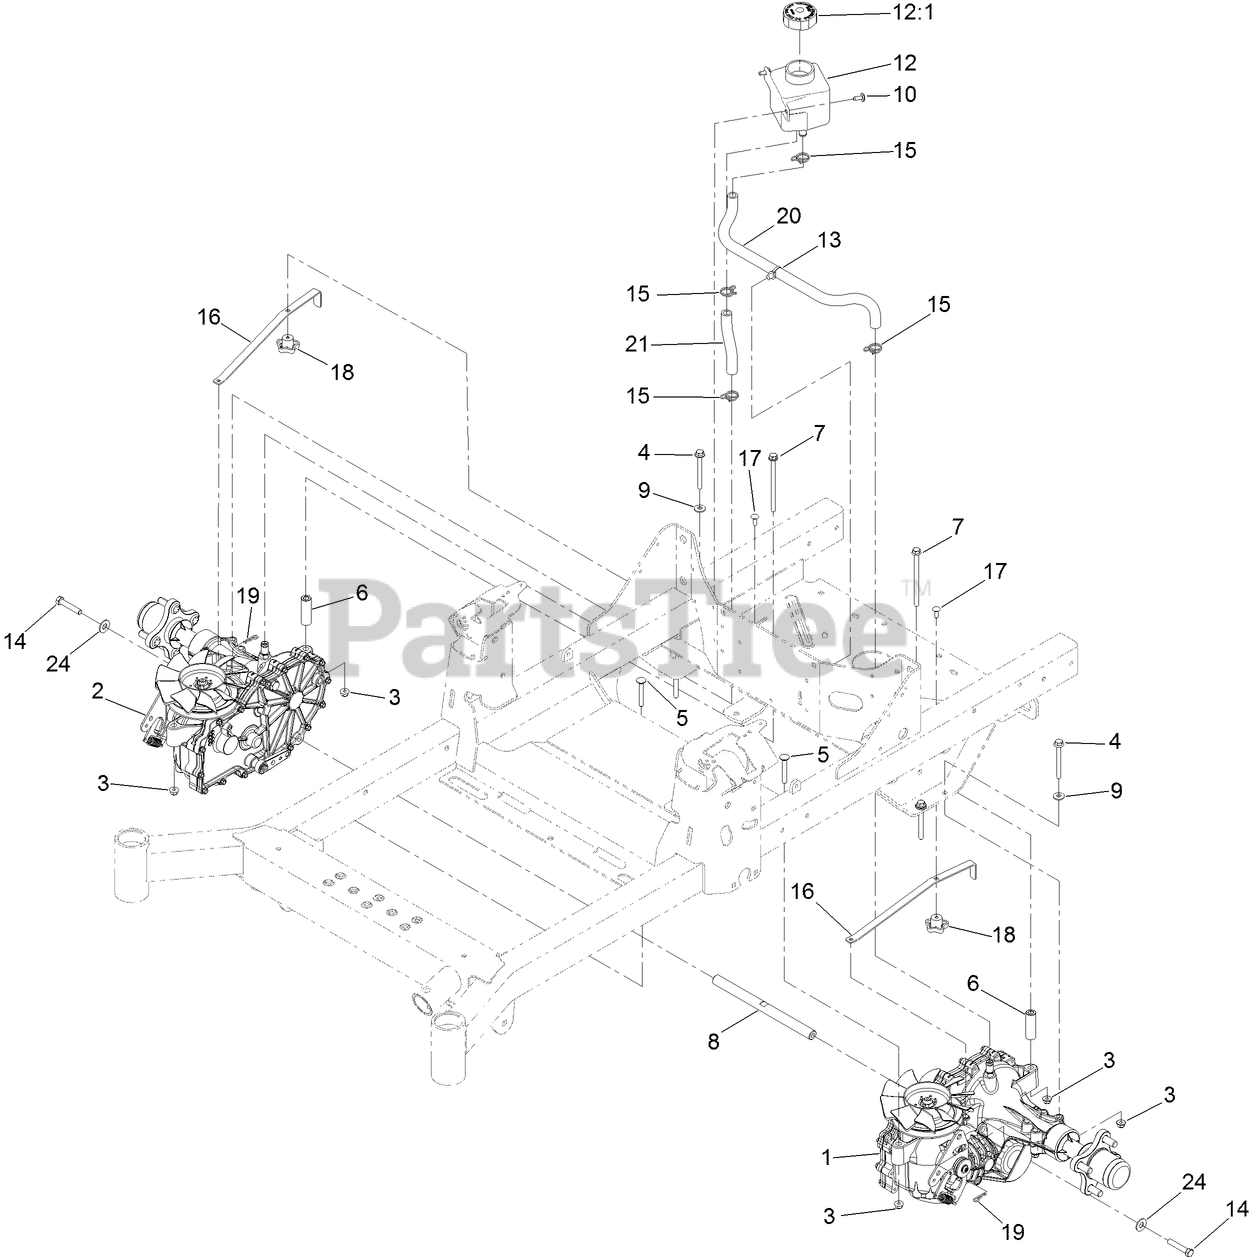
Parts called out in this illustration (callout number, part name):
1	LH TRANSAXLE ASM
2	RH TRANSAXLE ASM
3	NUT-HF, NI
4	SCREW-HHF
5	BOLT-CARR
6	SPACER-HYDRO
7	SCREW HHF
8	SHAFT-SPACER
9	WASHER-SPRING
10	SCREW-TORX
12	TANK-HYD
12:1	CAP-RESERVOIR, HYD
13	CLIP-TIE
14	SCREW-HH W/LOCTITE
15	CLAMP-HOSE
16	ARM-BYPASS, HYDRO
17	BOLT-CARR
18	KNOB-HANDLE
19	PIN-COTTER
20	HOSE-HYDRAULIC
21	HOSE-HYDRAULIC
24	WASHER-FLAT
